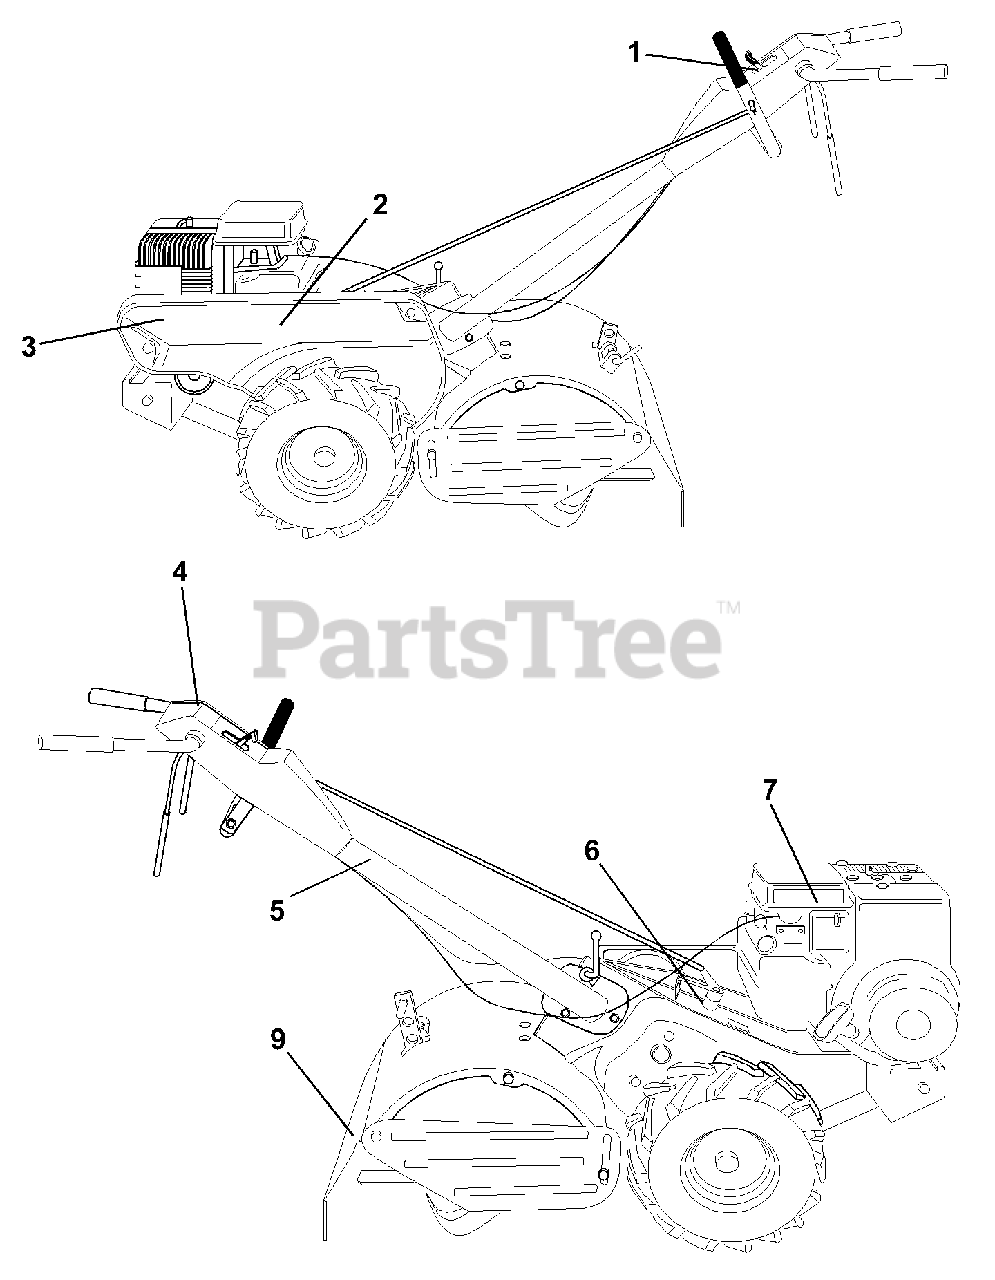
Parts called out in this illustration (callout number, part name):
1	Decal, Logo
2	Decal, Nameplate
3	Decal, Logo
4	Decal, Instruction, Tilling
5	Decal, Hand Placement
6	Decal, Shift Indicator
7	Decal, Caution
9	Decal, Warning, Rotating Tines
